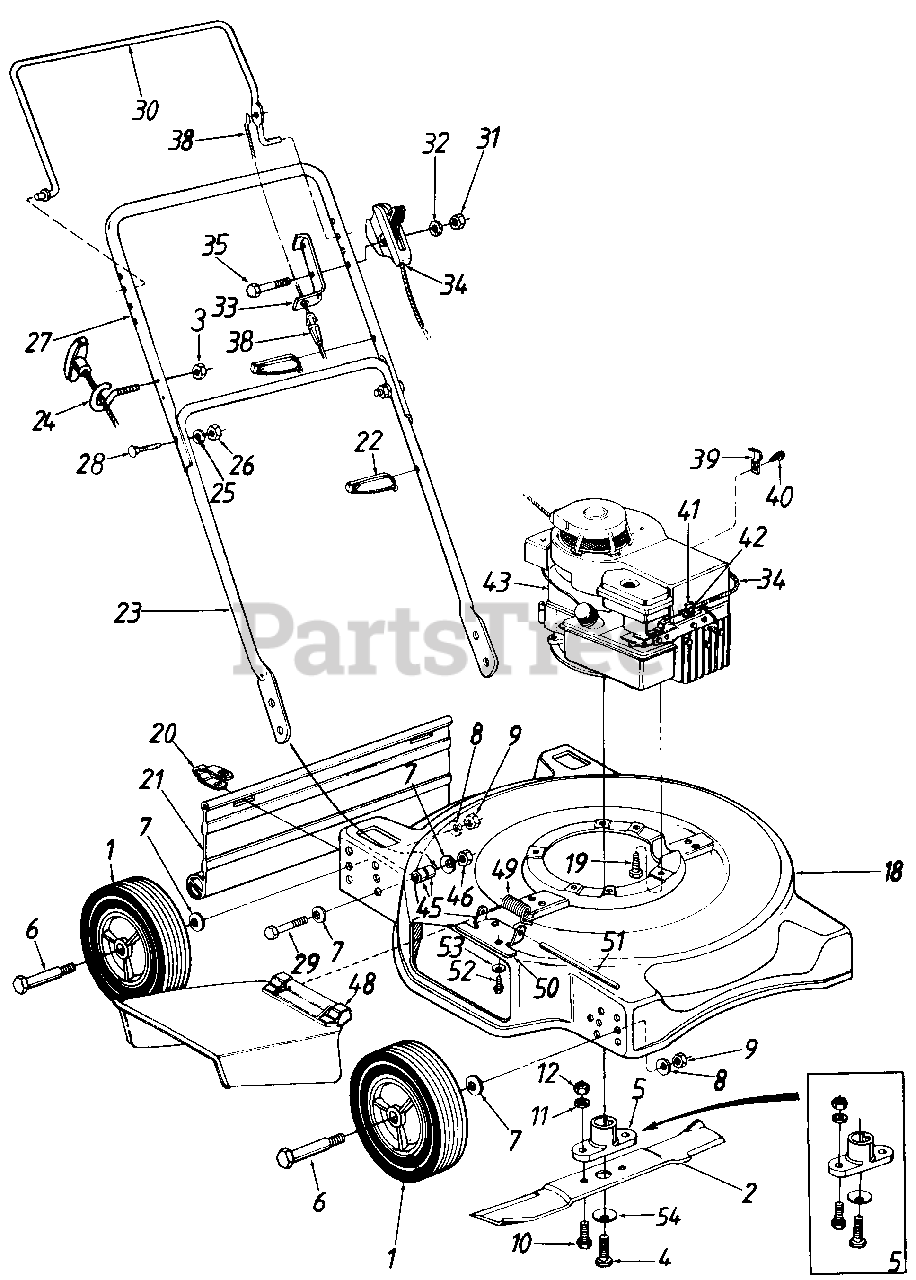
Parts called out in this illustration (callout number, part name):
1	Wheel Ass'y. Complete
2	20" Blade
3	Hex L-Nut 1/4-20 Thd.
4	Hex Bolt 3/8-24 x 1.5" Lg.
5	Blade Adapter Kit (Keyed)
7	Bell-Wash. .380" I.D. x .88"
8	Bell-Wash. 39" l.D. x 1.13"
9	Hex Nut 3/8-16 Thd.
10	Hex Bolt 3/8-24 x 1" Lg.
11	L-Wash. 3/8" I.D.
12	Hex Nut 3/8-24 Thd.
18	20" Deck Ass'y.
19	Hex Wash. Hd. Scr. 3/8-16 x 1" Lg.
20	Hinge Clip
21	Rear Flap 16.75n Lg.
22	Cable Tie
23	Lower Handle
24	Rope Guide Bolt
25	L-Wash. 5/16n l.D.
26	Hex Nut 5/16-18 Thd.
27	Upper tlandle
28	Curved Carriage Bolt 5/16-18 x 1.38" Lg.
29	Hex Bolt 3/8-24 x 1.5" Lg.
30	Control Handle
31	Hex Nut 1/4-20 Thd.
32	Spr. Wash. .265n l.D. x .562"
33	Cable Mounting Bracket
34	Throttle Control Ass'y. Comp.
35	Hex Bolt 1/4-20 x 1.875" Lg.
38	Control Cable-36"
39	Casing Clamp
40	Hex B-Tap Scr. #10 x .38" Lg.
41	Casing Clamp
42	Hex Wash. Hd. AB-Tap Scr. #8 x .50" Lg.
43	Engine
46	Hex L-Nut 3/8-24 Thd.
48	Chute Deflector Ass'y.
49	Torsion Spring
50	Adapter Plate
51	Hinge Pin
52	Hex Self-Tap Scr. 1/4-20 x .5"
53	Bell-Wash. 1/4" I.D.
54	Bell-Wash..39" I.D.
